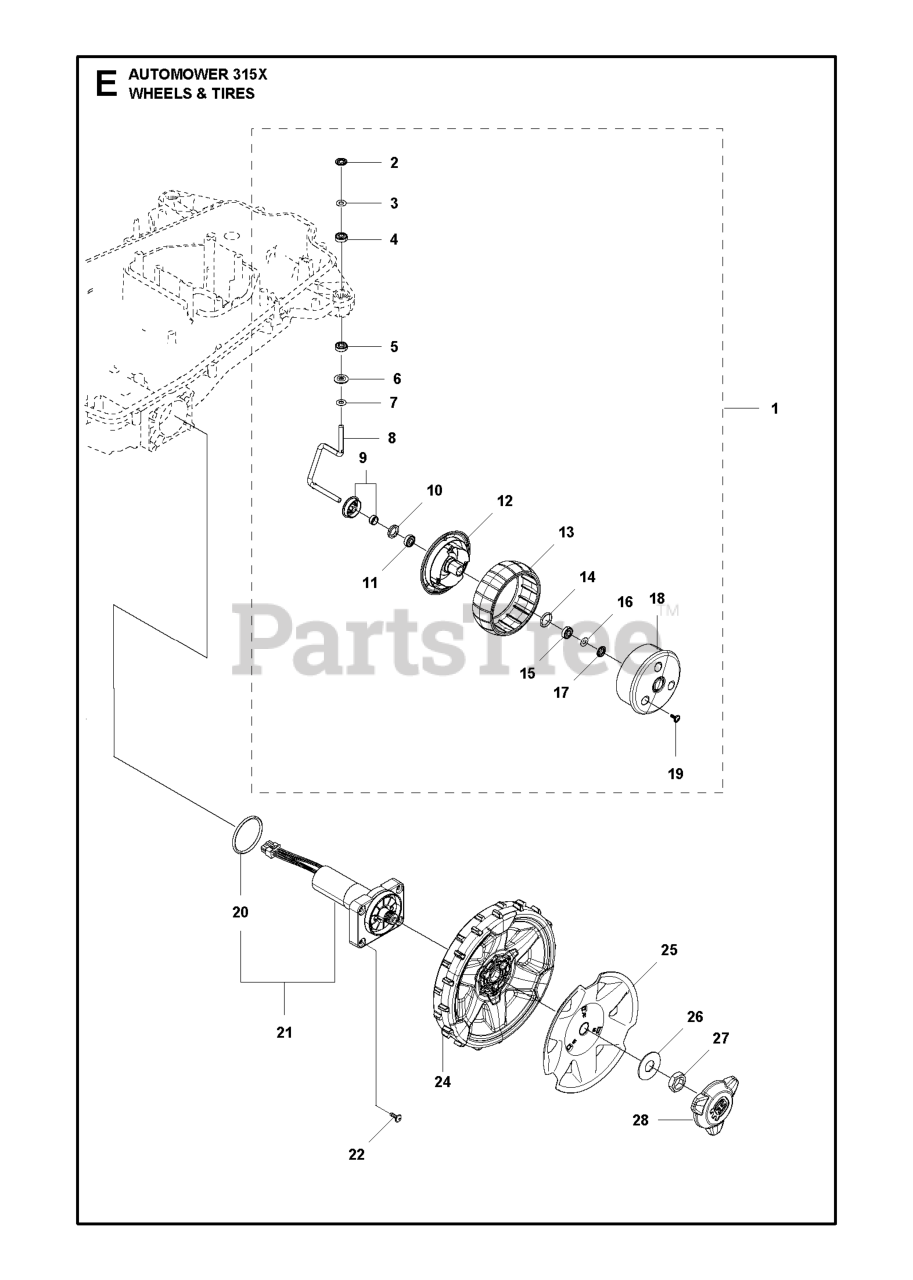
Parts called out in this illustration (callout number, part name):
1	WHEEL KIT FRONT
2	LOCKWASHER STARLOCK SS 6MM GEO
3	WASHER FRONT WHEEL 6MM
4	BALL BEARING SINGLE ROW S696
5	BALL BEARING SINGLE ROW S696
6	WASHER
7	WASHER FRONT WHEEL 6MM
8	SPINDLE FRONT WHEEL 6 MM
9	SHIELD KIT
10	SEALING 12X18X3
11	BALL BEARING SINGLE ROW S696
12	WHEEL FRONT WHEEL INSIDE
13	WHEEL RUBBER TYRE
14	O-RING 2,62X15,54
15	BALL BEARING SINGLE ROW S696
16	WASHER FRONT WHEEL 6MM
17	LOCKWASHER STARLOCK SS 6MM GEO
18	WHEEL FRONT WHEEL OUTSIDE
19	SCREW 14MM
20	O-RING LIGHT GREY
22	SCREW ITXPANT
25	WHEEL COVER PAINTED
26	WASHER WASHER REAR WHEEL 16X40
27	HEXAGON THIN NUT
28	HUB CAP REAR WHEEL NO CENTER P
